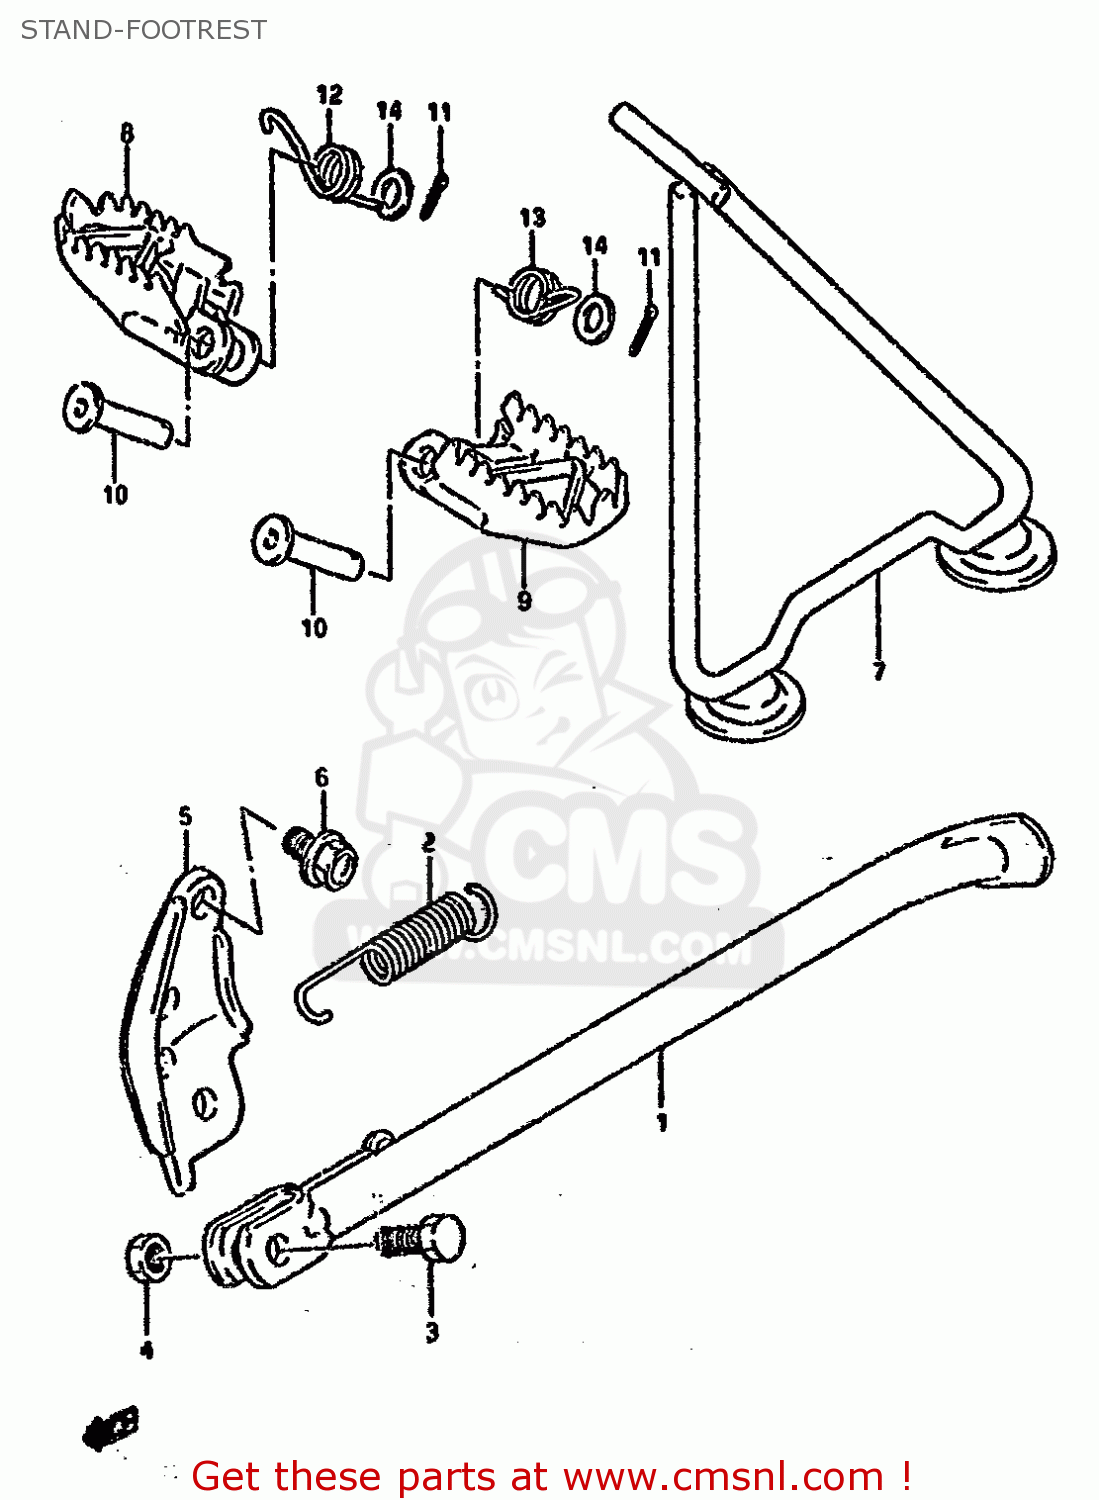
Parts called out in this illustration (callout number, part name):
1	STAND,PROP(BLACK)
2	SPRING
3	BOLT(10X30)
4	NUT
5	BRACKET,PROP STAND(BLACK)
6	BOLT
7	STAND COMP
8	FOOTREST,R
9	FOOTREST,L
10	PIN(10X41.5)
11	PIN 25X20
12	SPRING
13	SPRING
14	WASHER
